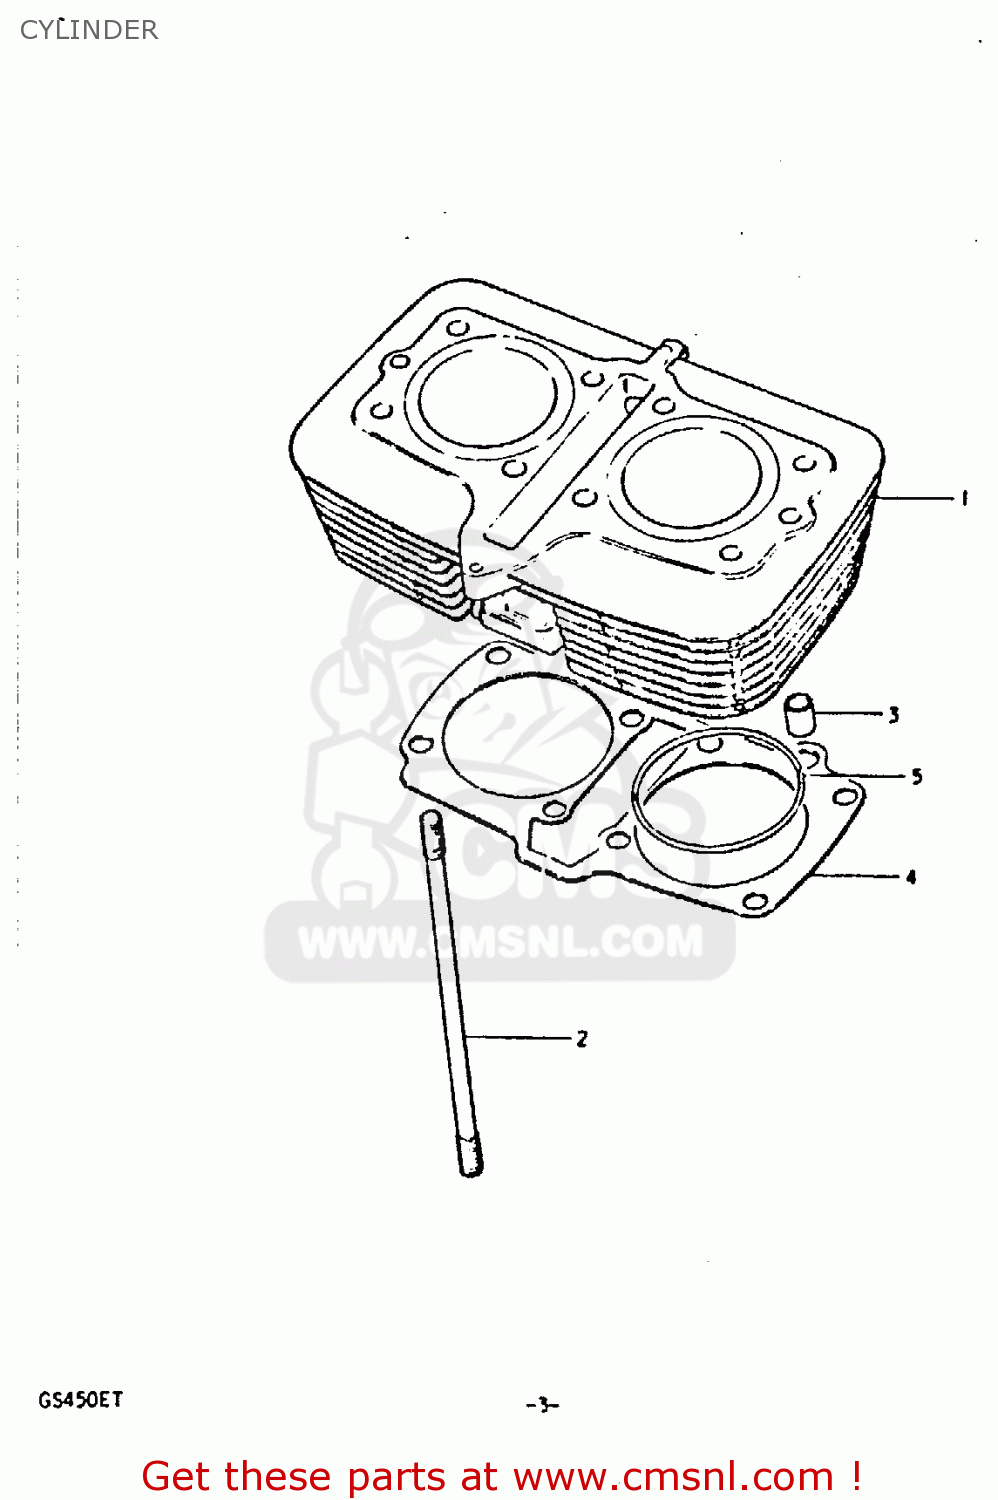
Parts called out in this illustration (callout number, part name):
1	CYLINDER
2	STUD
3	PIN
4	GASKET,CYLINDER (MCA)
5	O RING(D:2,ID:74)
